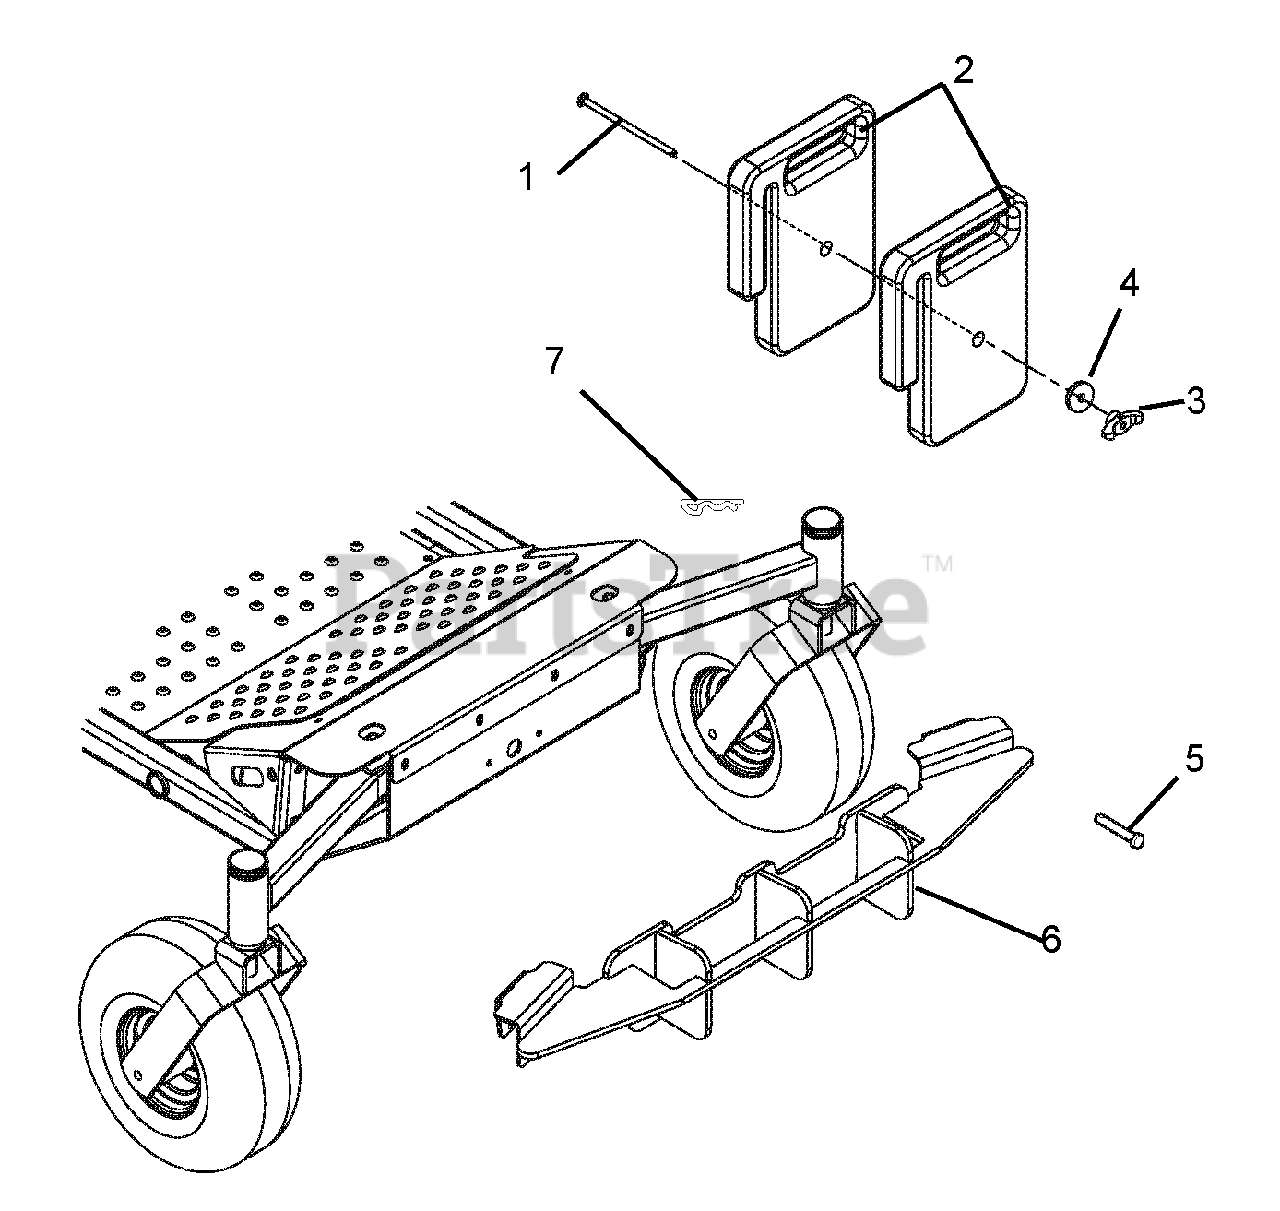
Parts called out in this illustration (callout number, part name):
1	Bolt .312-18 x 4.5
2	Counterweight
3	Knob, Wing .312-18 UNC (Tool-less hardware option)
4	Washer, Flat Steel .406 x 1.50 x .245
5	Pin-Clevis .368/.373 x 3.25
6	Weldment, Weight Plate
7	Hair Pin
